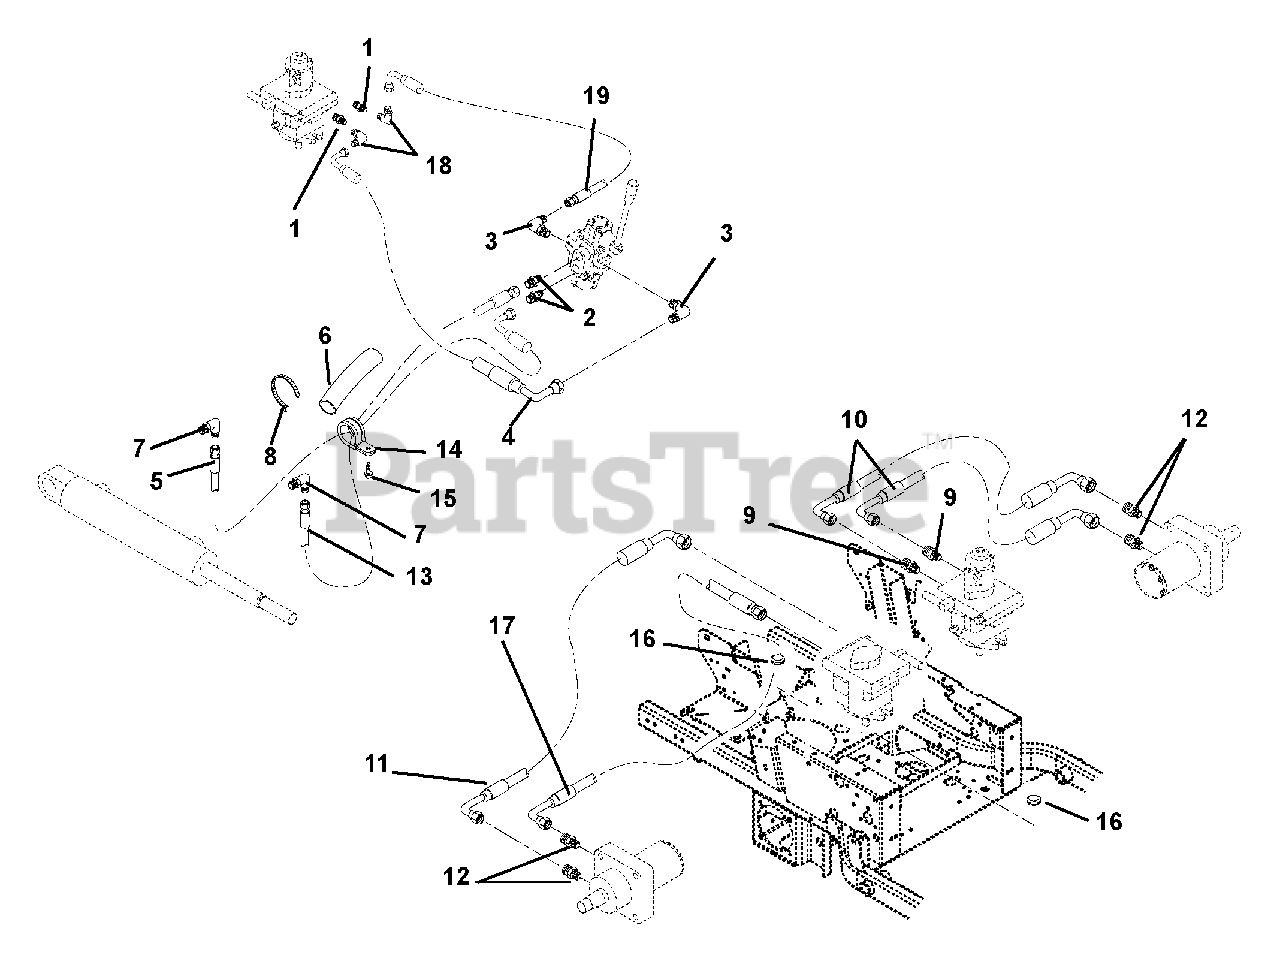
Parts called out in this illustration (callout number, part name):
1	Fitting, Hydraulic
2	Fitting, Hydraulic
3	Fitting, Hydraulic Elbow
4	Hose, Hydraulic
5	Hose, Hydraulic
6	Sleeve, Protective
7	Fitting, Hydraulic Elbow
8	Cable Tie
9	Adapter, Hydraulic
10	Hose, Hydraulic
11	Hose, Hydraulic
12	Adapter, Hydraulic
13	Hose, Hydraulic
14	Clamp, Steel 1.0
15	Screw-Tapping .25-20 X .50 Hex Washer Head Thread
16	Grommet, 1.25
17	Hose, Hydraulic
18	Fitting, Hydraulic Elbow
19	Hose, Hydraulic
